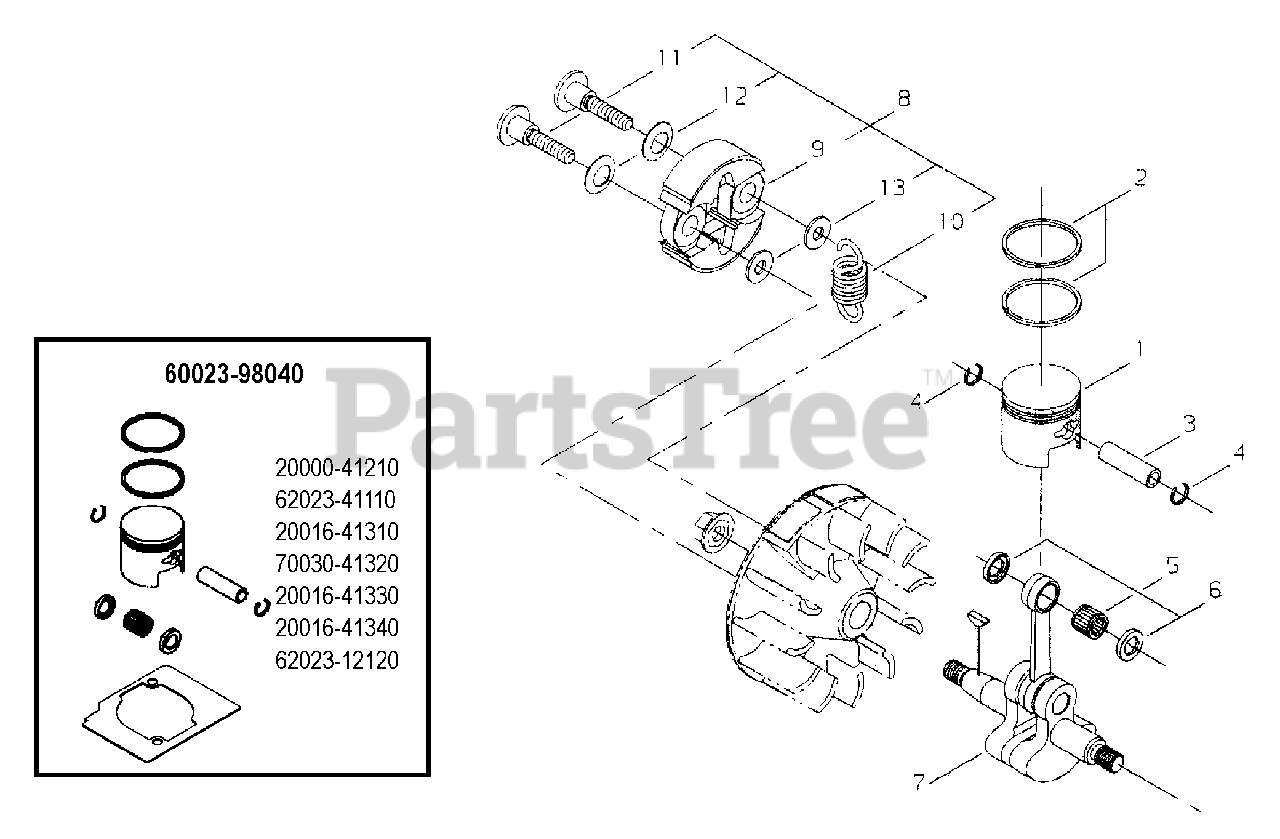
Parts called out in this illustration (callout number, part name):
1	PISTON
2	RING, PISTON
3	PIN, PISTON
4	RING, RETAINING
5	BEARING, NEEDLE
6	WASHER, THRUST
7	CRANKSHAFT ASSY
8	CLUTCH ASSY
9	SHOE, CLUTCH
10	SPRING, CLUTCH
11	BOLT, CLUTCH
12	WASHER - SPRING
13	WASHER - 6
60023-98040	PISTON ASSY
